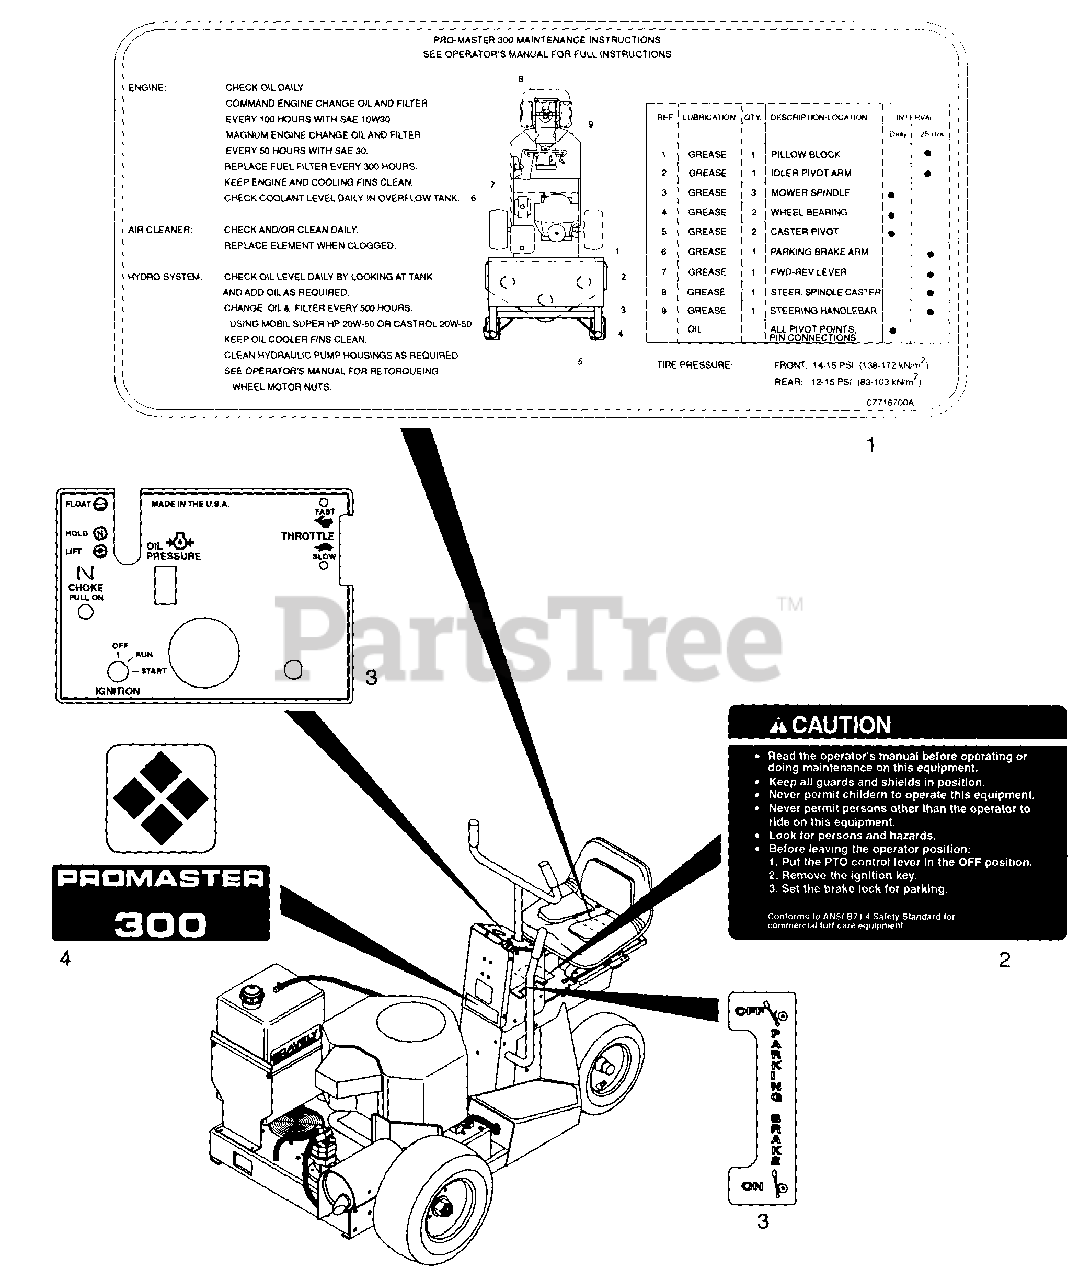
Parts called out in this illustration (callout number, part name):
1	Decal, PM-300 Maint/Caution
2	Decal - Safety Instruction
3	Decal Set - PM-300
4	Decal Set, PM-300
